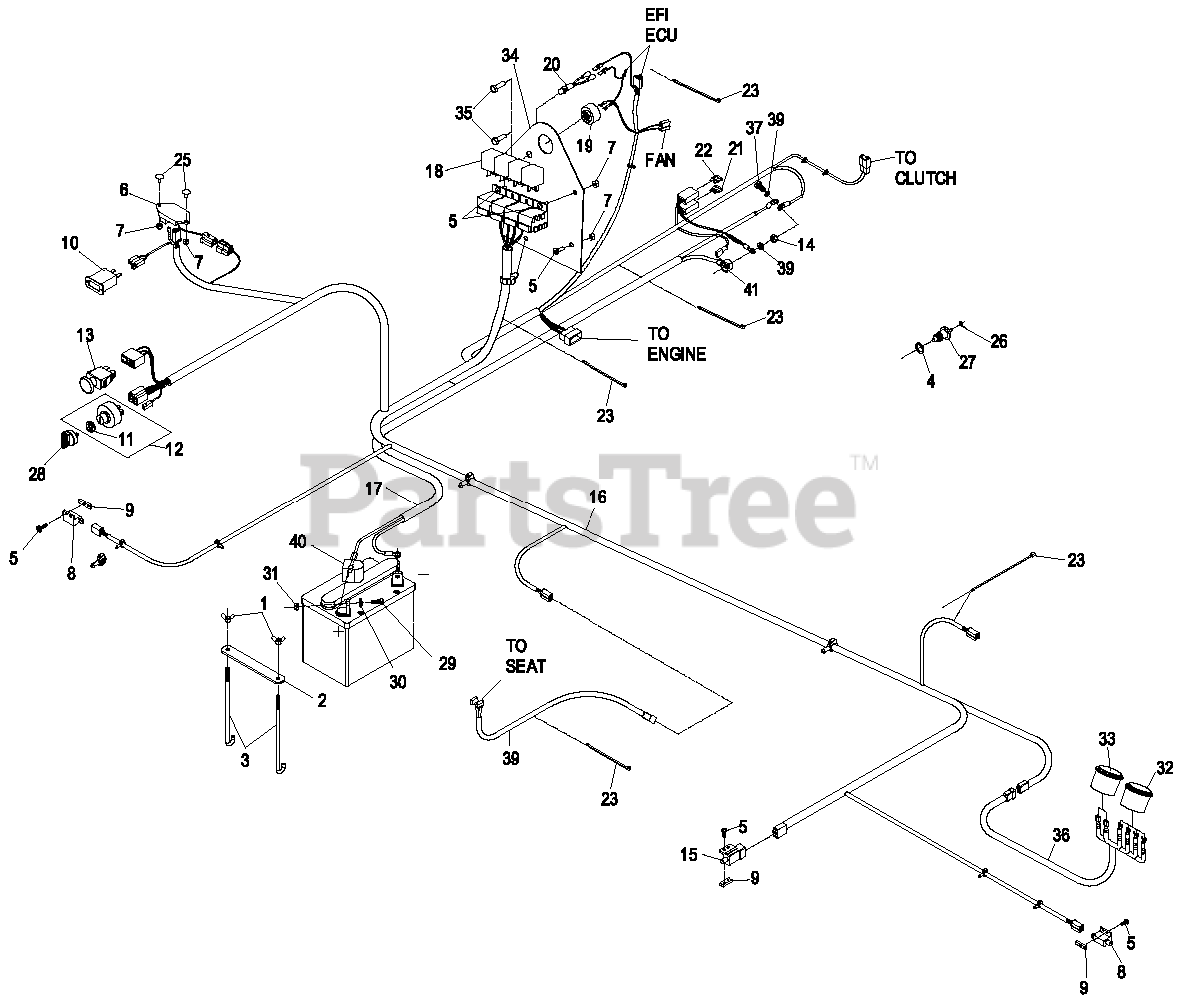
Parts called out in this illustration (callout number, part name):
1	WINGNUT
2	STRAP-HOLDDOWN, BATTERY
3	BOLT-HOLDDOWN
4	WASHER-ALUMINUM
5	SCREW-PPH
6	MODULE-DELAY, SEAT
7	NUT-LOCK, NI
8	SWITCH-OPEN, NORMALLY
9	PLATE-TAPPED
10	METER-HOUR
11	NUT-SWITCH, IGNITION
12	ASM,SWITCH W/NUT
13	SWITCH-PTO
14	Nut, Hex M8-125
16	HARNESS, WIRE LZ 29 LKA
17	ASM, BATTERY CABLE
19	ALARM-TONE, DUAL
20	INDICATOR-LED, RED
21	FUSE-BLADE TYPE, 30 AMP
22	FUSE-BLADE TYPE, 20 AMP
23	TIE-PLASTIC
25	BOLT-CARR
27	SENDER-TEMPERATURE
28	KEY-IGNITION
29	SCREW-HH
30	WASHER-FLAT
32	GAUGE,TEMP W/ ALERT
33	GAUGE-VOLTMETER
34	ASM,ELECT.PNL W/ DECALS
35	SCREW-HWHTF
36	HARNESS,GAGE
37	SCREW-HH
38	WASHER-PLAIN
39	HARNESS-WIRING, SEAT
40	INSULATOR-BATTERY
41	INSULATOR-SOLENOID
